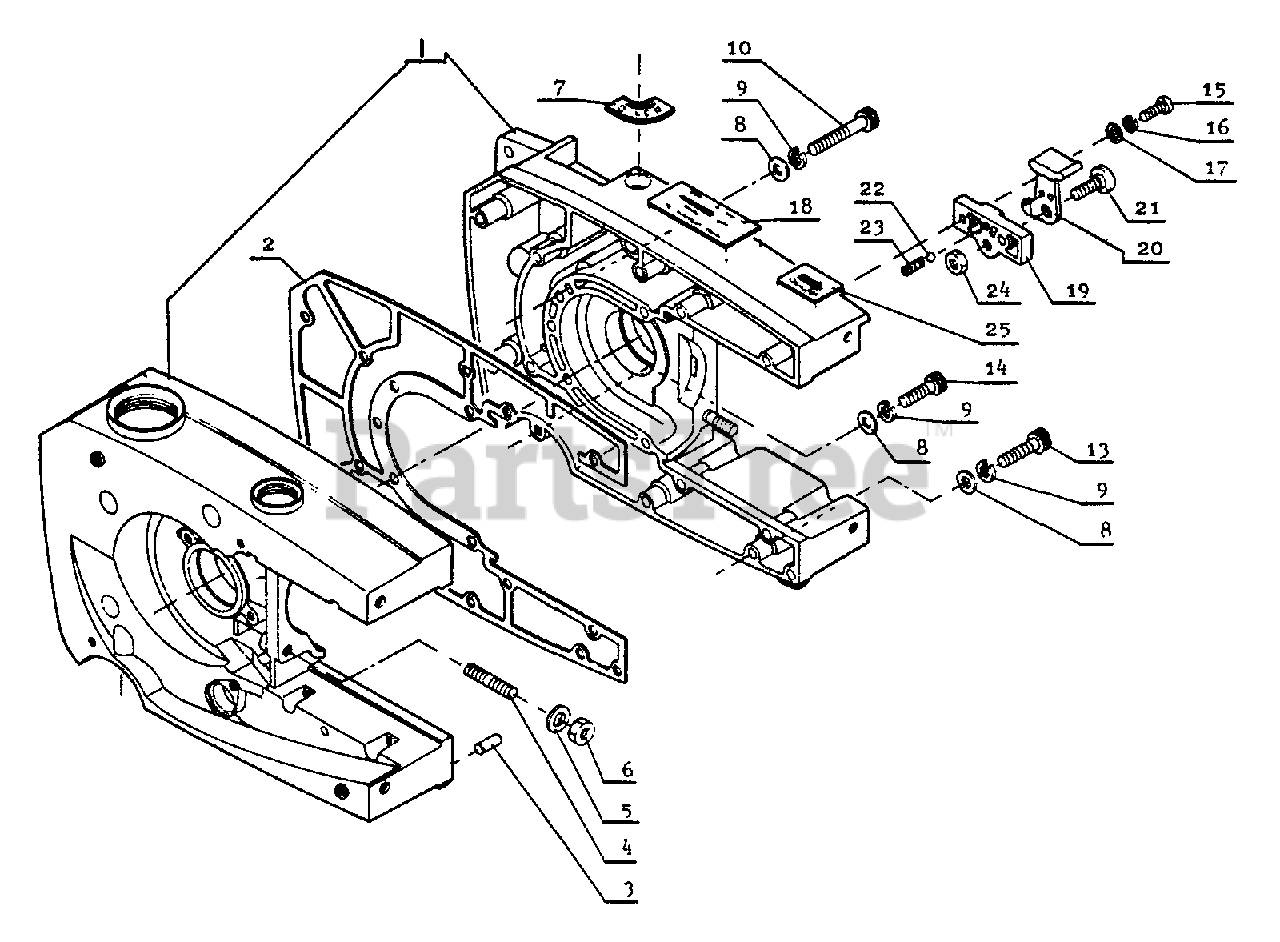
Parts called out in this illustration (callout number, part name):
1	CRANKCASE KIT
2	GASKET, CRANKCASE
3	PIN, LOCATING 5×10
5	WASHER 6.5×11.5×0.8
6	NUT, HEX M6
7	LABEL - CAUTION
8	WASHER
9	WASHER, SPRING 5
10	SCREW - 5×35
13	BOLT 5×30
14	BOLT M5×18
15	SCREW 4×10
16	WASHER, SPRING 4 MM
17	WASHER 4 MM
18	LABEL, CAUTION - OIL
19	BRACKET
20	LEVER, DECOMPRESSION
21	SCREW, SET
22	VALVE, BALL
24	NUT M5
25	LABEL - DECOMPRESSION
